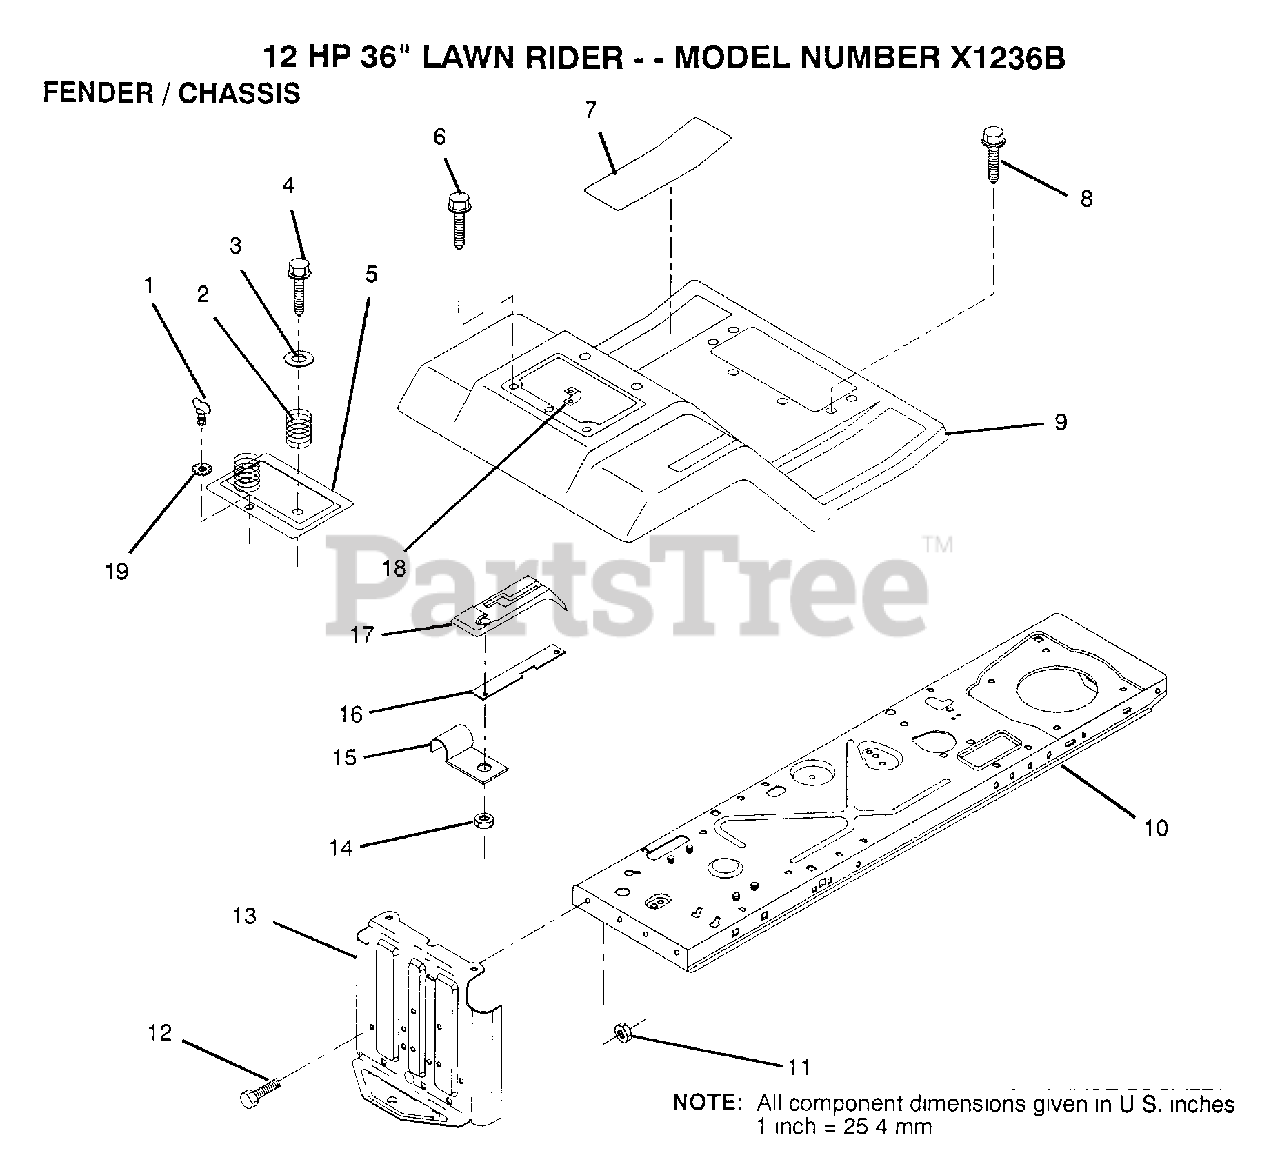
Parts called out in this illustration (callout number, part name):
1	STUD.1/4.TURN
2	SPRING COMPRESSIO
3	WASHER
4	SCREW
6	SCREW LT
7	PAD FOOTREST
8	SCREW
9	"FENDER,FOOTREST"
10	FRAME ASS'Y
12	BOLT
13	DRAWBAR
14	NUT
15	"CLIP,INSULATOR"
16	"SHIFT LOCK, BAR"
17	CONSOLE SHFT 5SP
18	RECEPTACLE LT
19	RETAINER LT
